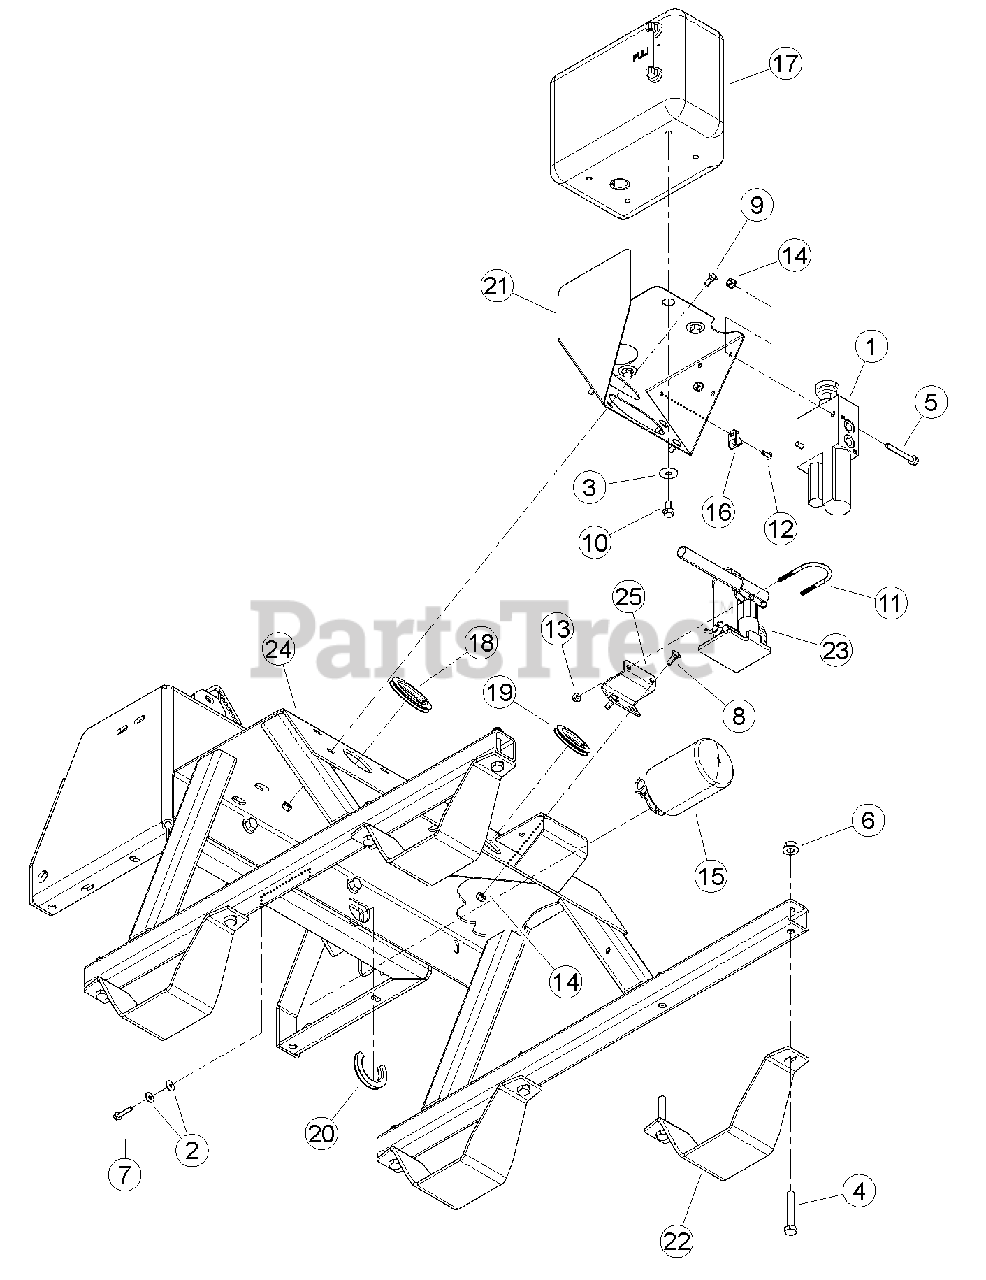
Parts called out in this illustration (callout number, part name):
1	VALVE, HYDRAULIC CONTROL
2	WASHER, 1/4" FLAT ZP
3	WASHER, 3/8" FENDER ZP
4	BOLT, 1/2 X 3 GR5 HEX HD ZP
5	BOLT, 5/16 X 2-1/2 FLANGE NC
6	NUT, 1/2-13 NYLOCK FLANGE
7	BOLT, 1/4 X 1-1/4 FLANGE NC
8	BOLT, 5/16 X 7/8" GR5 CRG NC ZP
9	BOLT, 5/16 X 3/4 GR5 CRG NC ZP
10	BOLT, 3/8 X 3/4" SERRATED FLANGE
11	U-BOLT, 1/4 X 1-1/2 PIPE
12	RIVET, AL BLIND 1/4 X 3/4 DOME HEAD
13	NUT, 1/4-20 NYLOCK FLANGE
14	NUT, 5/16-18 NYLOCK FLANGE
15	ASSEMBLY, HYDRAULIC FILTER
16	CLAMP, CABLE MOUNT
17	TANK, HYDRAULIC
18	TRIM, SLOT EDGE COVER
19	TRIM, SLOT EDGE COVER
20	TRIM, SLOT EDGE COVER
21	WELDMENT, RESERVOIR BASE
22	PAD, PTO CHIPPER
23	JACK, HYDRAULIC 2 TON
24	WELDMENT, PTO STAND
25	MOUNT, JACK
